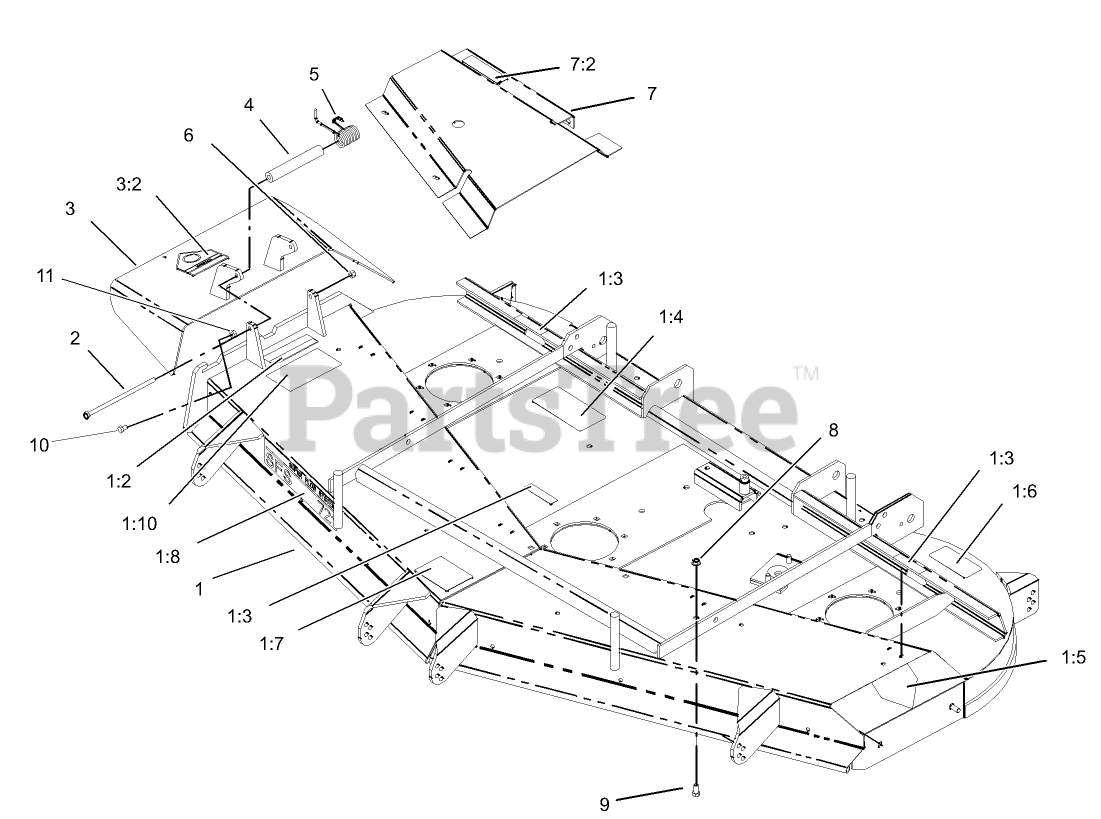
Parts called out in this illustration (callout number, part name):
1	Deck ASM
1:2	DECAL-WARNING
1:3	DECAL-COVER, MISSING
1:4	DECAL-ROUTING, BELT
1:5	DECAL-DANGER
1:6	DECAL-TORQUE, BLADE BOLT
1:7	DECAL-WHEEL, GAGE
1:8	DECAL-DECK
1:10	DECAL-DANGER, THROWN OBJECT
2	SCREW-HH
3	Deflector ASM
3:2	DECAL-DANGER
4	SPACER
5	SPRING-TORSION
6	NUT-LOCK, NI
7	RH COVER W/DECAL ASM
7:2	DECAL-DANGER
8	NUT-HHF, WHIZ
9	SCREW-HH
10	SCREW-HH
11	NUT-HF
